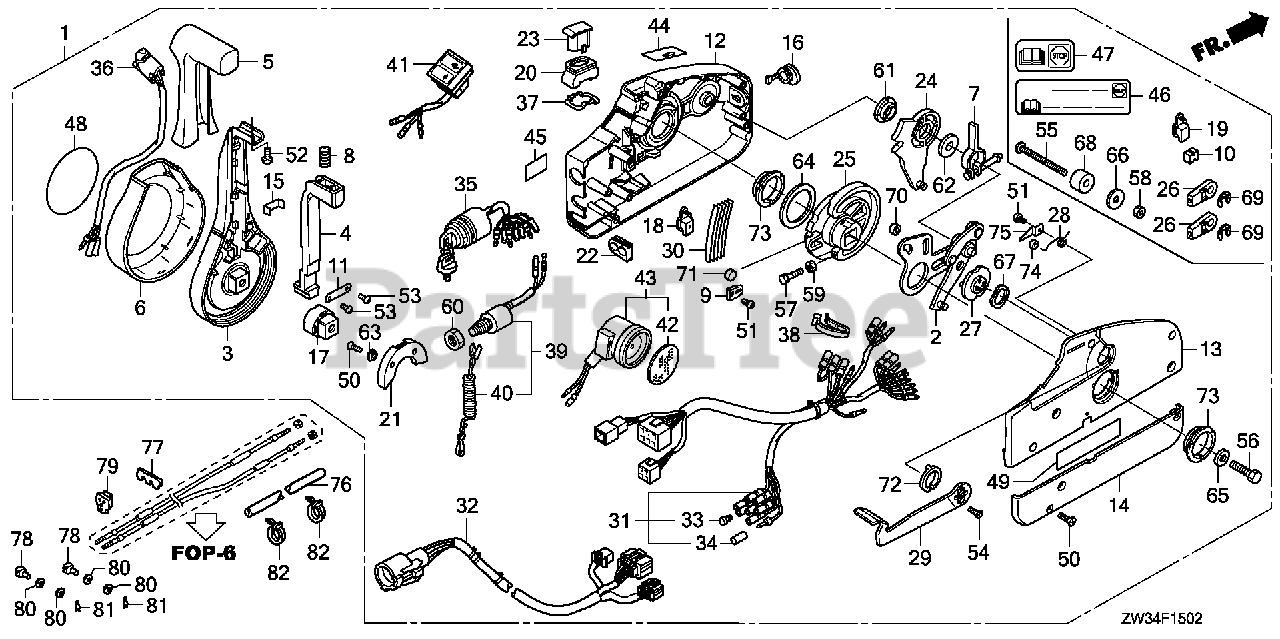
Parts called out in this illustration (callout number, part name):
1	BOX ASSY., REMOTE CONTROL (NHK MEC)
2	PLATE ASSY.
3	LEVER, HAND
4	ARM, NEUTRAL LOCK
5	GRIP
6	COVER, LEVER
7	ARM ASSY., BRAKE
8	SPRING (2)
9	CLIP, DETENT
10	SPACER (1) (LOOSE PARTS)
11	BRACKET
12	HOUSING, FR.
13	HOUSING, RR.
14	PANEL, BACK
15	BRACKET, WIRE CLAMP
16	CAP, RUBBER
17	ADJUSTER
18	COVER, POWER TRIM-TILT WIRE (LOOSE PARTS)
19	COVER, POWER TRIM-TILT WIRE (LOOSE PARTS)
20	SEAL, RUBBER
21	HOLDER, NEUTRAL LOCK
22	GROMMET, WIRE (14)
23	CAP, TROLLING CONTROL SWITCH BLANK
24	GEAR ASSY., SHIFT
25	GEAR, DRIVE
26	TERMINAL, CABLE (LOOSE PARTS)
27	DRUM ASSY., FREE THROTTLE
28	SPRING (1)
29	LEVER, FREE THROTTLE
30	SPRING, DETENT
31	CABLE ASSY., REMOTE CONTROL (B)
32	CABLE ASSY., SWITCH PANEL
33	PLUG, CONNECTOR (INNER) (TROLLING CONTROL)
34	PLUG, CONNECTOR (OUTER) (ENGINE NO.)
35	SWITCH ASSY., COMBINATION (SINGLE) (DUAL)
36	SWITCH ASSY., POWER TRIM-TILT
37	PLATE, SWITCH
38	BAND, WIRE
39	SWITCH ASSY., EMERGENCY STOP
40	WIRE, EMERGENCY (SINGLE) (DUAL)
41	LAMP ASSY., INDICATION (2-LED)
42	PLATE, TURN SIGNAL BUZZER DUAL QTY = (2) (SINGLE)
43	BUZZER, WARNING DUAL QTY = (2) (SINGLE)
44	MARK, FAST IDLE
45	MARK, EMERGENCY STOP (US) (LOOSE PARTS)
46	MARK, EMERGENCY STOP (US) (LOOSE PARTS)
48	MARK, EMBLEM
49	LABEL, SIGP
50	SCREW (5X18)
51	SCREW (4X6)
52	SCREW (5X10)
53	SCREW (4X10)
54	SCREW (5X12)
55	SCREW (6X90) (LOOSE PARTS)
56	BOLT (8X50)
57	BOLT (5X25)
58	NUT (6MM) (LOOSE PARTS)
59	NUT (5MM)
60	NUT, HEX. (16MM) DUAL QTY = (2) (SINGLE)
61	BEARING (1)
62	WASHER (3)
63	WASHER (4)
64	WASHER (5)
65	WASHER (8MM)
66	WASHER (7) (LOOSE PARTS)
67	WASHER, WAVE
68	SPACER (2) (LOOSE PARTS)
69	E-RING (6MM) (LOOSE PARTS)
70	ROLLER, DRIVE GEAR CAM
71	ROLLER
72	BEARING (2)
73	BEARING (3)
74	ROLLER, FREE THROTTLE
75	CLIP, ROLLER
76	TUBE, CORRUGATED (28MM)
77	PLATE, REMOTE CONTROL CABLE
78	PIVOT, SHIFT
79	GROMMET, CASE (LOWER) (A)
80	WASHER, PLAIN (6MM) Use from Frame SN 4800713.
81	PIN, SPECIAL LOCK (6MM)
82	BAND, SELF-LOCK Use from Frame SN 3000253.
